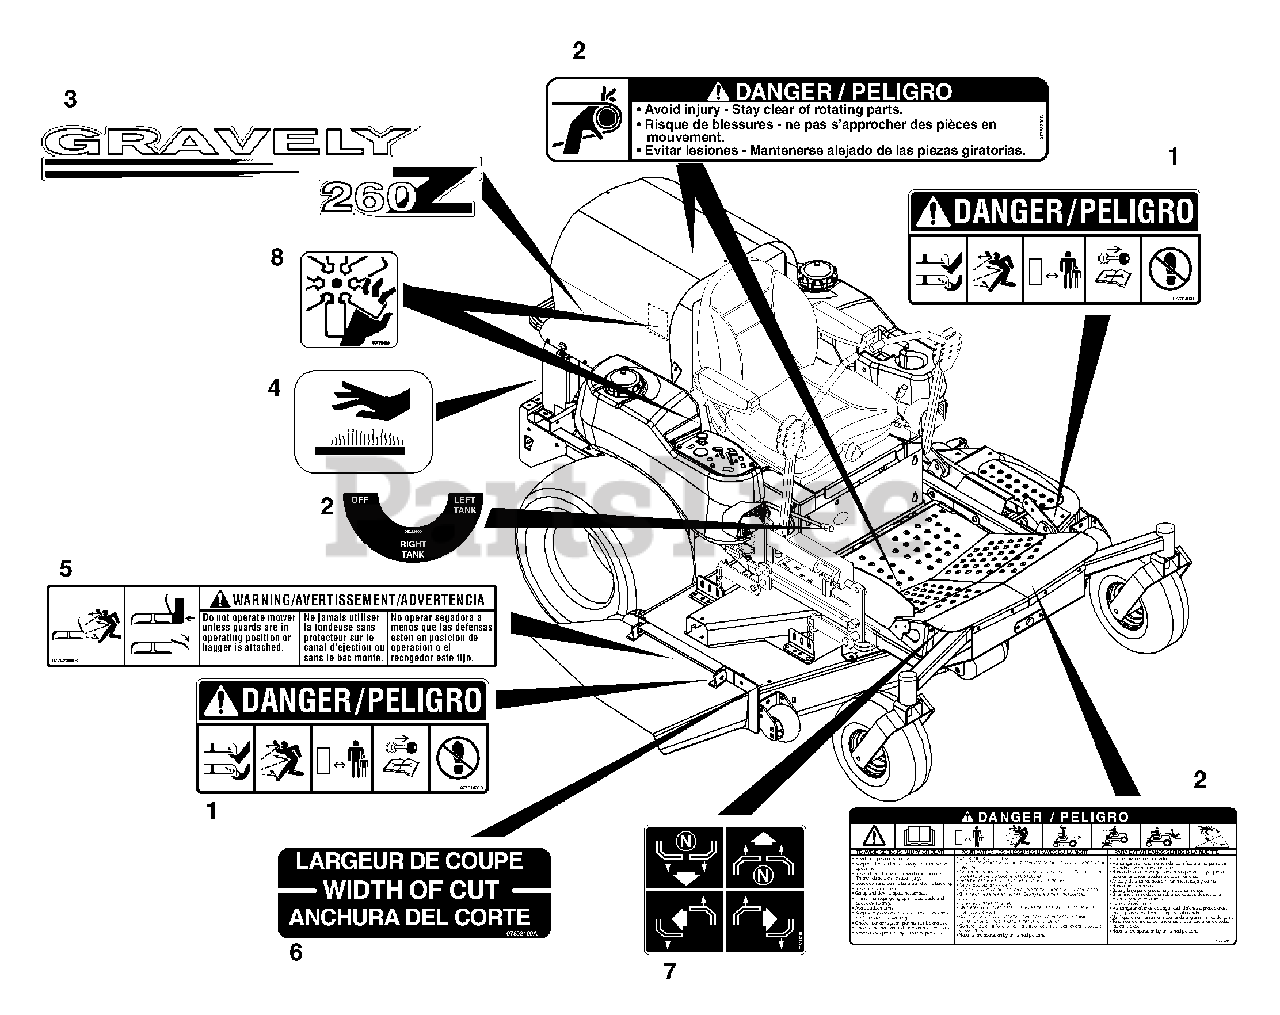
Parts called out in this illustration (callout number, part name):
1	Decal, Mower Pan Head Danger
2	Set, Decal-Common Danger/Fuel
3	Decal, PM-260Z Hood (058, 060, 318, 319)
3	Decal, PM-272Z Hood (059, 061)
4	Decal, Hot Surface
5	Decal, Warning
6	Decal, Width of Cut
7	Decal, Instructional
8	Decal, Danger Fan
